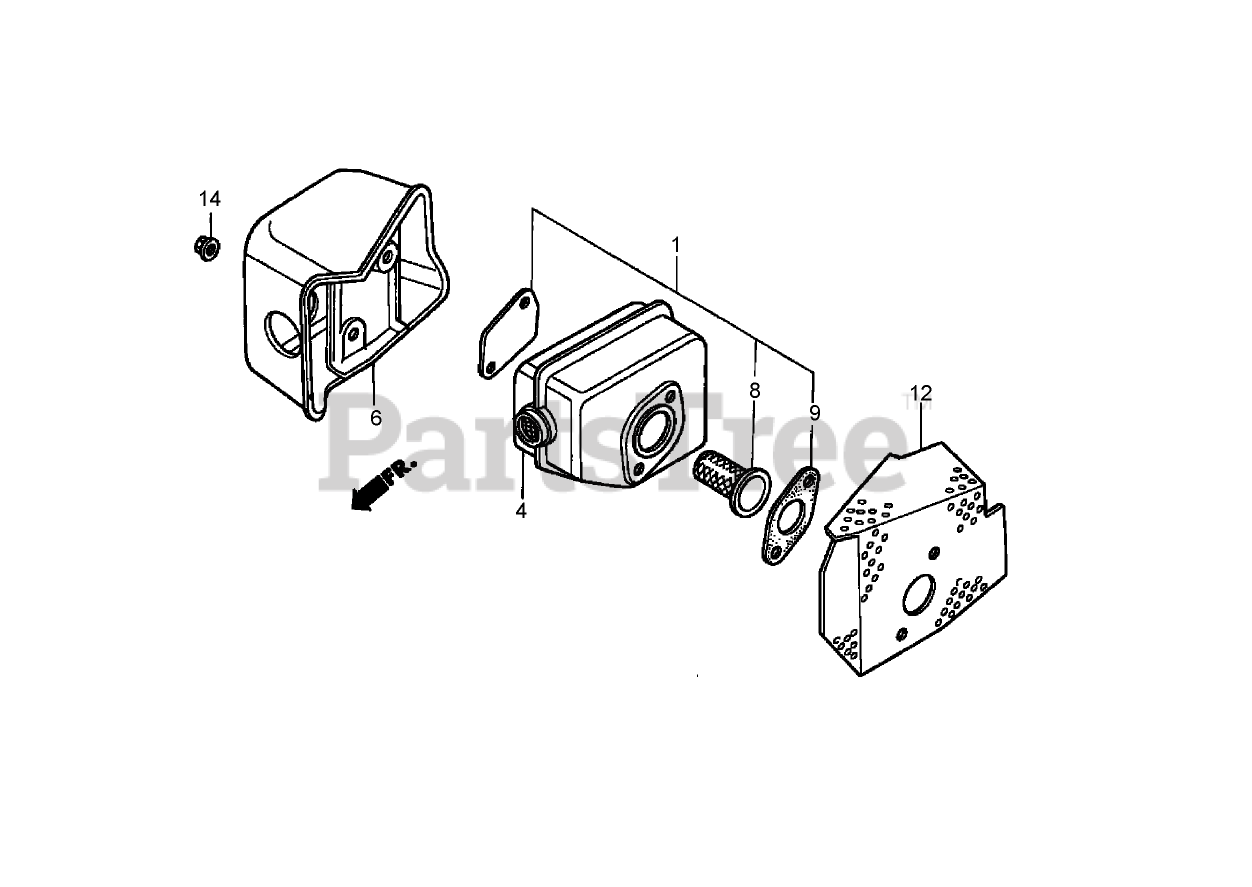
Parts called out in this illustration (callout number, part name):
1	SPARK ARRESTER KIT
4	Muffler
6	Protector-Muffler
8	SPARK ARRESTER KIT
8	SPARK Arrester Kit
9	Gasket-Muffler
12	Gasket-Muffler
14	NUT-LOCK, SELF (6 mm)
